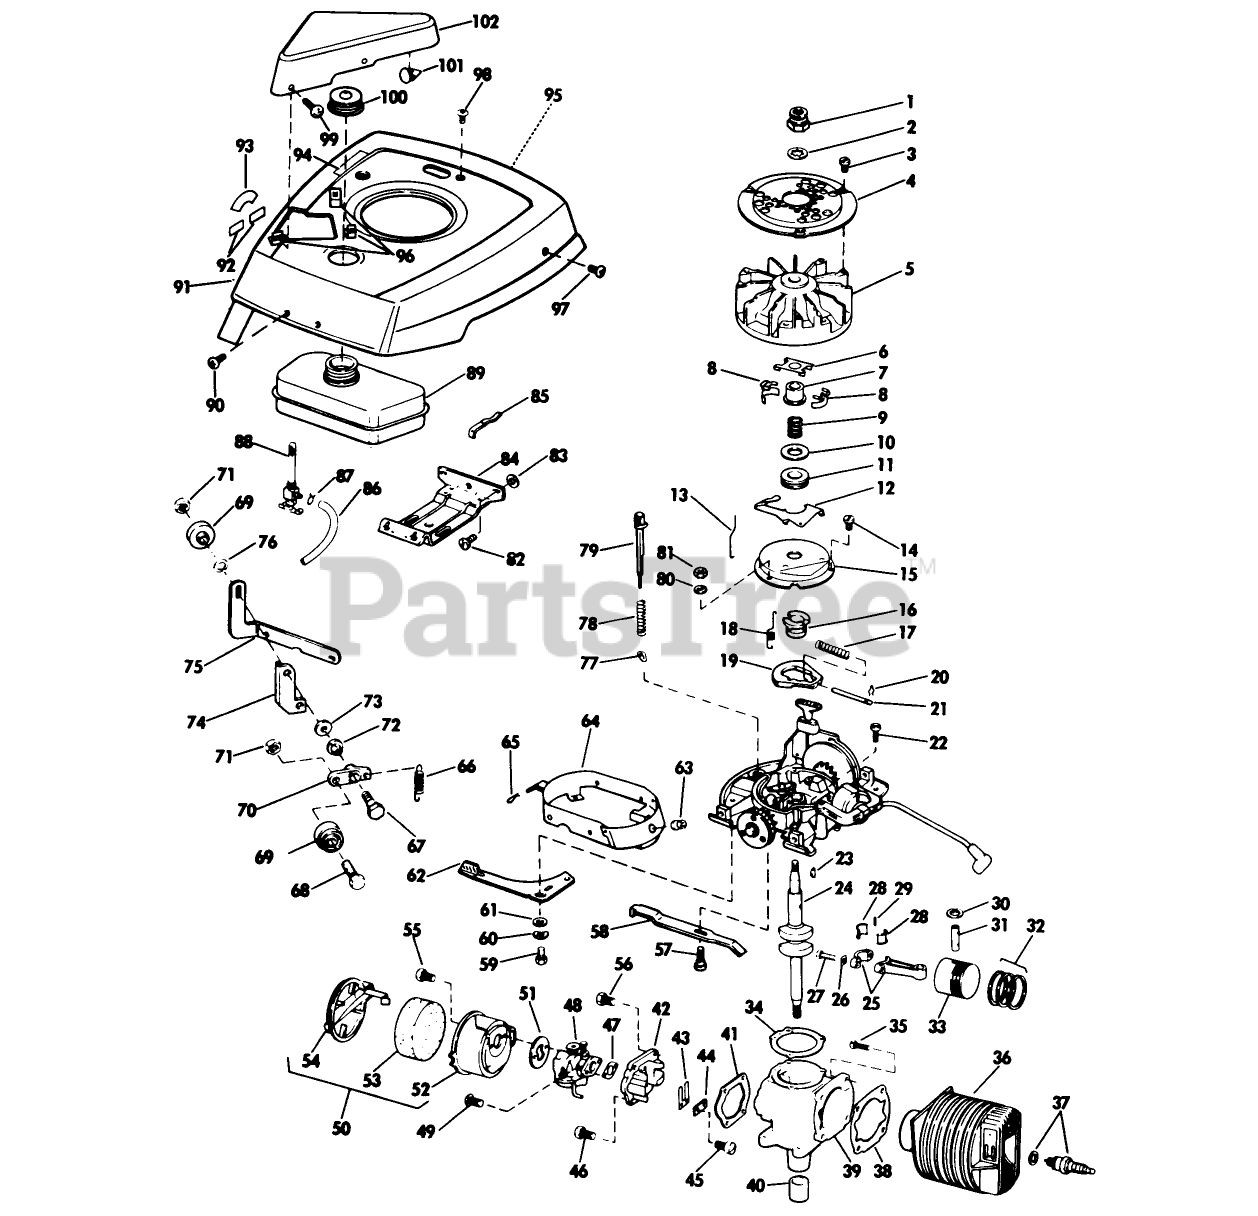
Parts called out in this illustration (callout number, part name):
7	COLLAR S
9	SPRING S
11	THRUST COLLAR S
12	LEVER-GOVERNOR S
14	SCREW S
15	DUST COVER S
16	SPARK ADV. S
17	SPARK ADV. SPRING S
19	FLYWEIGHT S
20	SPARK ADJ. SPRING
21	PIN,SPARK ADV. S
28	LINER ASM
30	RING-RETAINING
34	GASKET S
38	GASKET S
44	PLATE-BACKUP, REED
46	SCREW S
47	GASKET S
53	AIR FIL.ELEM S
55	SCREW S
56	SCREW S
63	NUT-CLIP
69	IDLER PULLEY
78	SPRING S
82	SCREW S
86	Gas Line
87	CLAMP - HOSE S
88	VALVE&SCREEN SM
97	SCREW S
